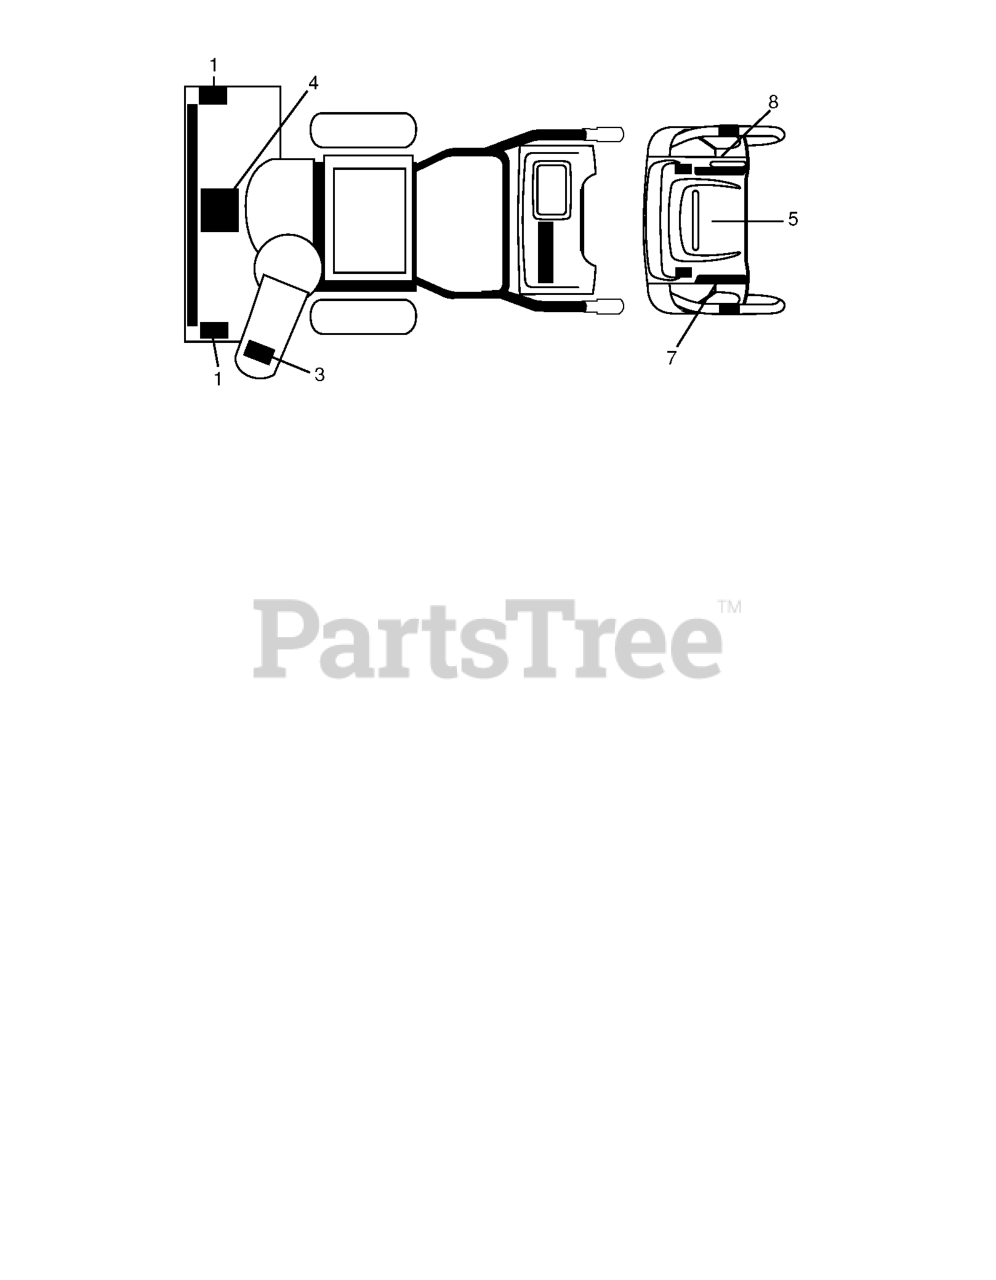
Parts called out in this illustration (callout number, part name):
1	DECAL.SNOWTHR.AUGER
3	DECAL.SNOWTHR.CHUTE.SAFETY
4	DECAL.SNOWTR.READ.OWN.MAN.E/F
5	DECAL.CONSOLE.SNOW.INST.ENG/FR
7	DECAL.CONS.LT.SPD/LEV/PWRST.
8	DECAL.CONS.RT.SPD/LEV/PWRST.
